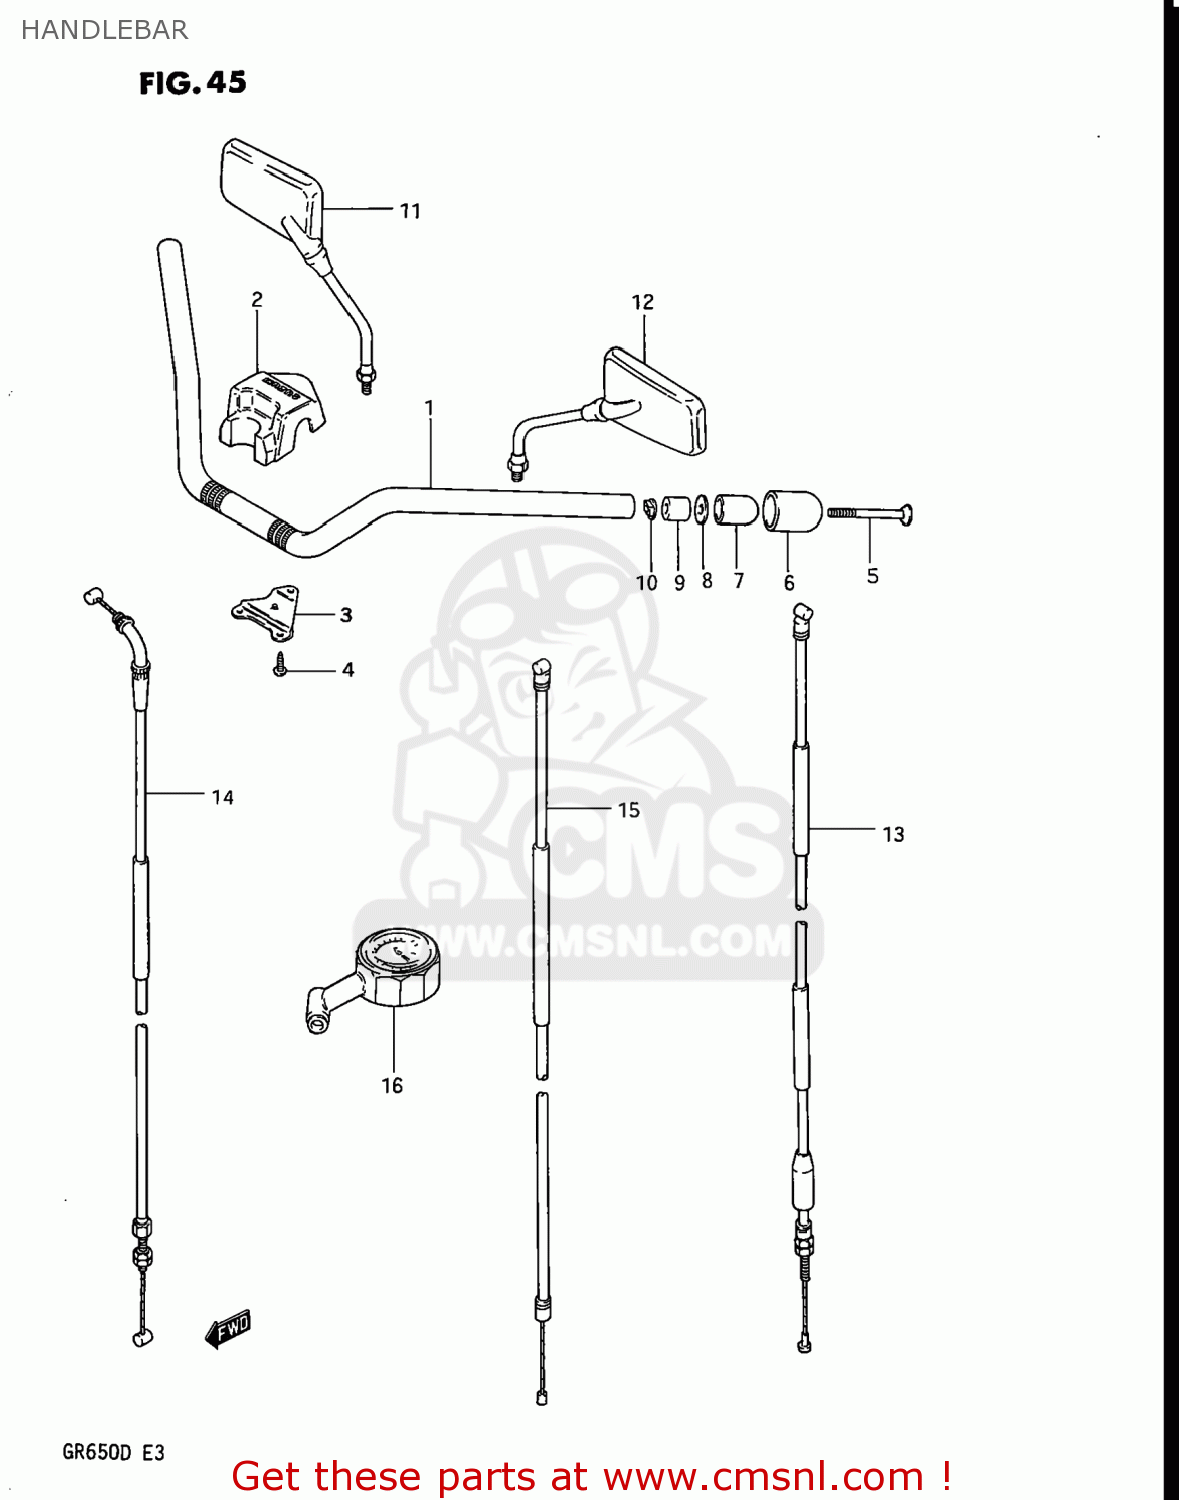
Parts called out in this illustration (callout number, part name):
1	HANDLEBAR,RIGHT
2	COVER,STEERING HEAD
3	BRACKET,STEERING HEAD
4	SCREW
5	SCREW 6X65
6	CAP,BALANCER
7	BALANCER,HANDLE
8	SPACER,BALANCER
9	EXPANDER,BALANCER
10	NUT
11	MIRROR ASSEMBLY,REAR VIEW
12	MIRROR ASSEMBLY,REAR VIEW
13	CABLE ASSY,CLUTCH
14	CABLE ASSEMBLY,THROTTLE
15	CABLE COMP,STARTER
16	GAUGE ASSY,AIR PRESSURE
